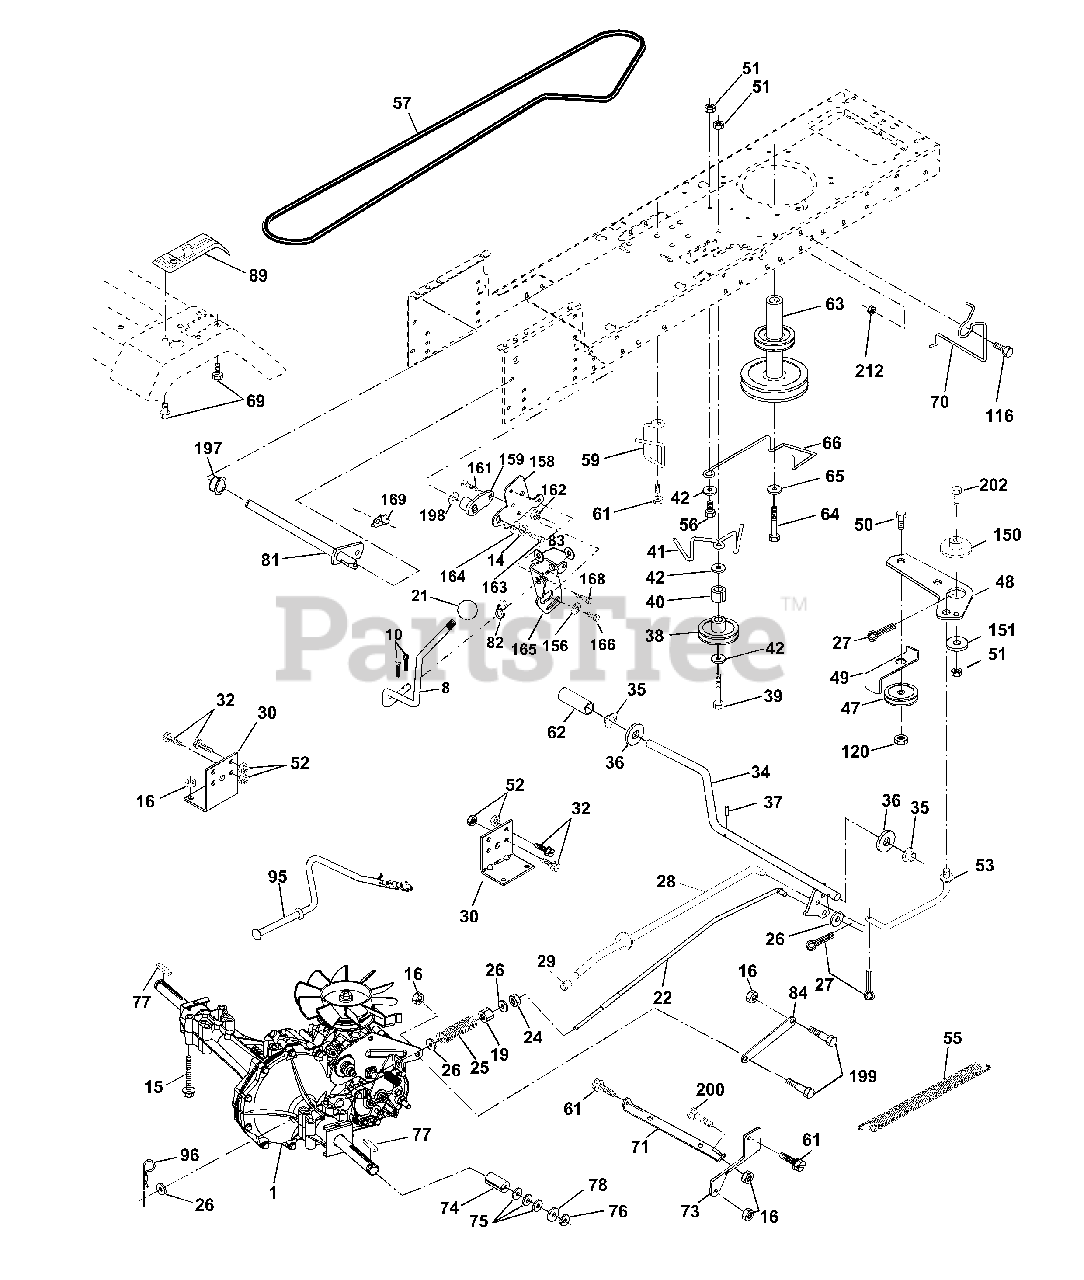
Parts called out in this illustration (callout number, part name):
8	Rod Shift Hydro LT
10	Pin Cotter 1/8 x 1 CAD
14	Washer Lock Hvy Helical
15	Bolt, Hex FLGHD 5/16-18 Gr. 5
16	Nut Lock Hex W/Ins 5/16-18 Unc P
19	Nut Lock Hex W/Wsh 3/8-16 Unc
21	Knob, Round 1/2-13
22	Rod, Brake Hydro
24	Nut
25	Spring, Brake Rod
26	Washer
27	Pin Cotter 1/8 x 3/4 CAD.
28	Rod, Parking Brake
29	Cap, Parking Brake
30	Bracket, Transaxle
32	Bolt Hex Hd 5/16-18 Unc x 3/4
34	Shaft, Foot Pedal
35	Bearing, Nylon
36	Washer
37	Pin, Roll
38	Pulley, Idler, Flat
39	Bolt
40	Spacer, Split
41	Keeper, Belt Idler
42	Washer 13/32 x 13/16 x 12 Gauge
47	Pulley, Idler, V-Groove
48	Bellcrank Clutch Grnd Drv STL
49	Retainer, Belt
50	Bolt
51	Nut Crownlock 3/8-16 UNC
52	Nut Crownlock 5/16-18 UNC
53	Link, Clutch
55	Spring, Return, Clutch
56	Bolt Fin Hex 3/8-16 x 1-1/4
57	V-Belt, Ground Drive
59	Keeper, Center Span
61	Screw Thdrol. 3/8-16 x .75
62	Cover, Pedal
63	Pulley, Engine
64	Bolt, Hex
65	Washer
66	Keeper Belt Engine
69	Screw
70	Guide Belt
71	Strap Torque Lh Hydro
73	Strap Torque Rh Hydro
74	Spacer, Axle
75	Washer 25/32 x 1-1/4 x 16 Gauge
76	E-Ring
77	Key, Square
78	Washer 25/32 x 1-5/8 x 16 Gauge
81	Shaft Asm. Cross Hydro
82	Spring Torsion T/A
83	Washer 17/32 x 3/4 x 16 Ga.
84	Link Transaxle
89	Console, Hydro
95	Control Asm Bypass Hydro
96	Retainer Spring 1" Zinc/Cad
116	Bolt Rdhd Sq Neck 3/8-16 x 1
120	Nut Lock Flg 3/8-16
150	Bushing Bellcrank
151	Washer 13/32 x 2 x 10 Ga.
156	Washer Srrted 5/16 ID x 1.125
158	Bracket Shift Mount
159	Hub Tapered Flange Shift Lt
161	Bolt Rdhd Sqnk 1/4-20 x 3/4 Gr 5
162	Nut Crownlock 1/4-20 Unc
163	Bolt Hex Fin 1/4-20 Unc x 1 Gr 5
164	Washer 5/8 x .281 x 10 Ga
165	Bracket Pivot Lever
166	Screw 5/16-18 x 5/8
168	Bolt Shoulder 5/16-18 x .561
169	Plate Fastening Lt
197	Nyliner Snap-In 5/8" ID
198	Washer Nyl 7/8 ID x .105
199	Bolt Shoulder 5/16-18 Unc
200	Bolt Rdhd Sqnk 5/16-18 Unc x 1
202	Bolt RDHD 3/8-16 x 1-1/2 Gr 5
212	Nut Hex Flg Lock
